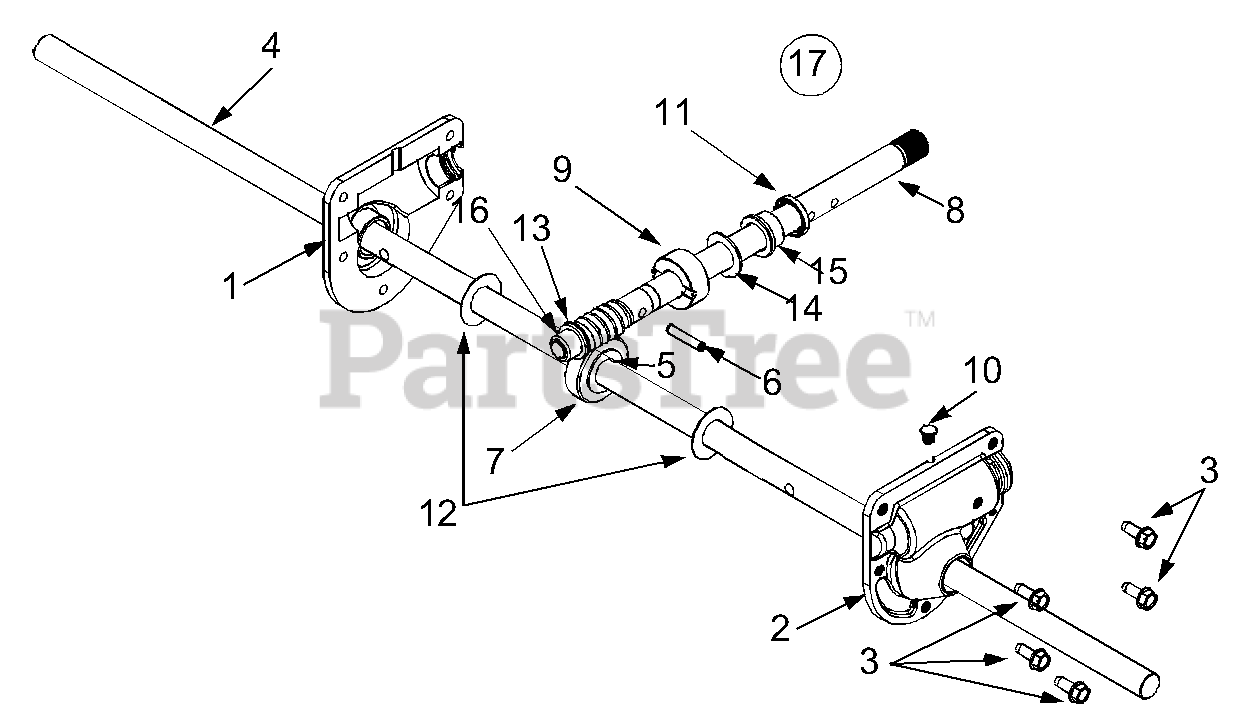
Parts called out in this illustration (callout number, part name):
1	RH Housing
2	LH Housing w/Fitting
3	Self Tapping Screw, 1/4-20 x .75
4	Spiral Axle, 28"
5	Hi-Pro Key, 3/16 x 5/8
6	Spring Spiral Pin, .25 x 1.25
7	Worm Gear, 20-tooth
8	Worm Shaft
9	Thrust Collar
10	Grease Plug
11	Grease Seal
12	Flat Washer, .76 x 1.5 x .030
13	Flat Washer, .508 x 1.0 x .020
14	Flat Washer, .76 x 1.5 x .060
15	Flange Bearing, .75 x 1.0 x .59
16	Flange Bearing, .503 ID x .75 OD
17	Gear Assembly 28"
